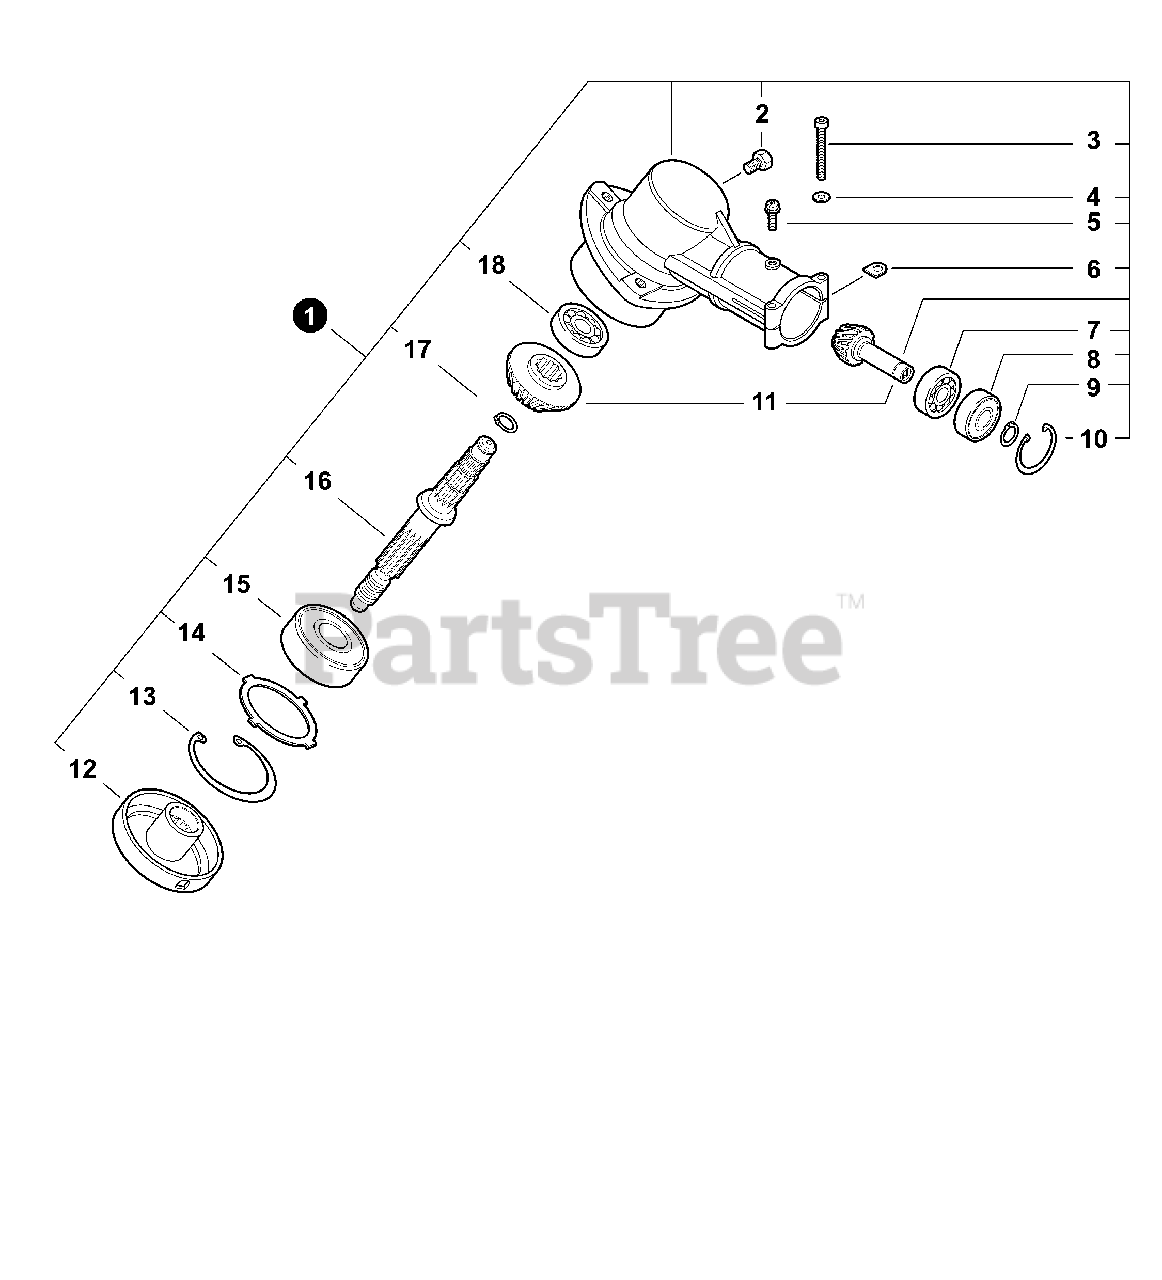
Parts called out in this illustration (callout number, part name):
1	GEAR CASE ASSY
2	BOLT M8×8
3	BOLT 5×35 SP
4	WASHER, FLAT 5.5×10×0.8
5	SCREW 5×10
7	BEARING, BALL 6900
8	BEARING, BALL 6900Z
9	RING, SNAP Ø10
10	RING, SNAP Ø22
11	GEAR SET
12	PLATE, ADAPTOR - UPPER
13	RING, SNAP Ø32
15	BEARING, BALL 6201
16	SHAFT, GEAR
17	RING, SNAP Ø12
18	BEARING, BALL 609
